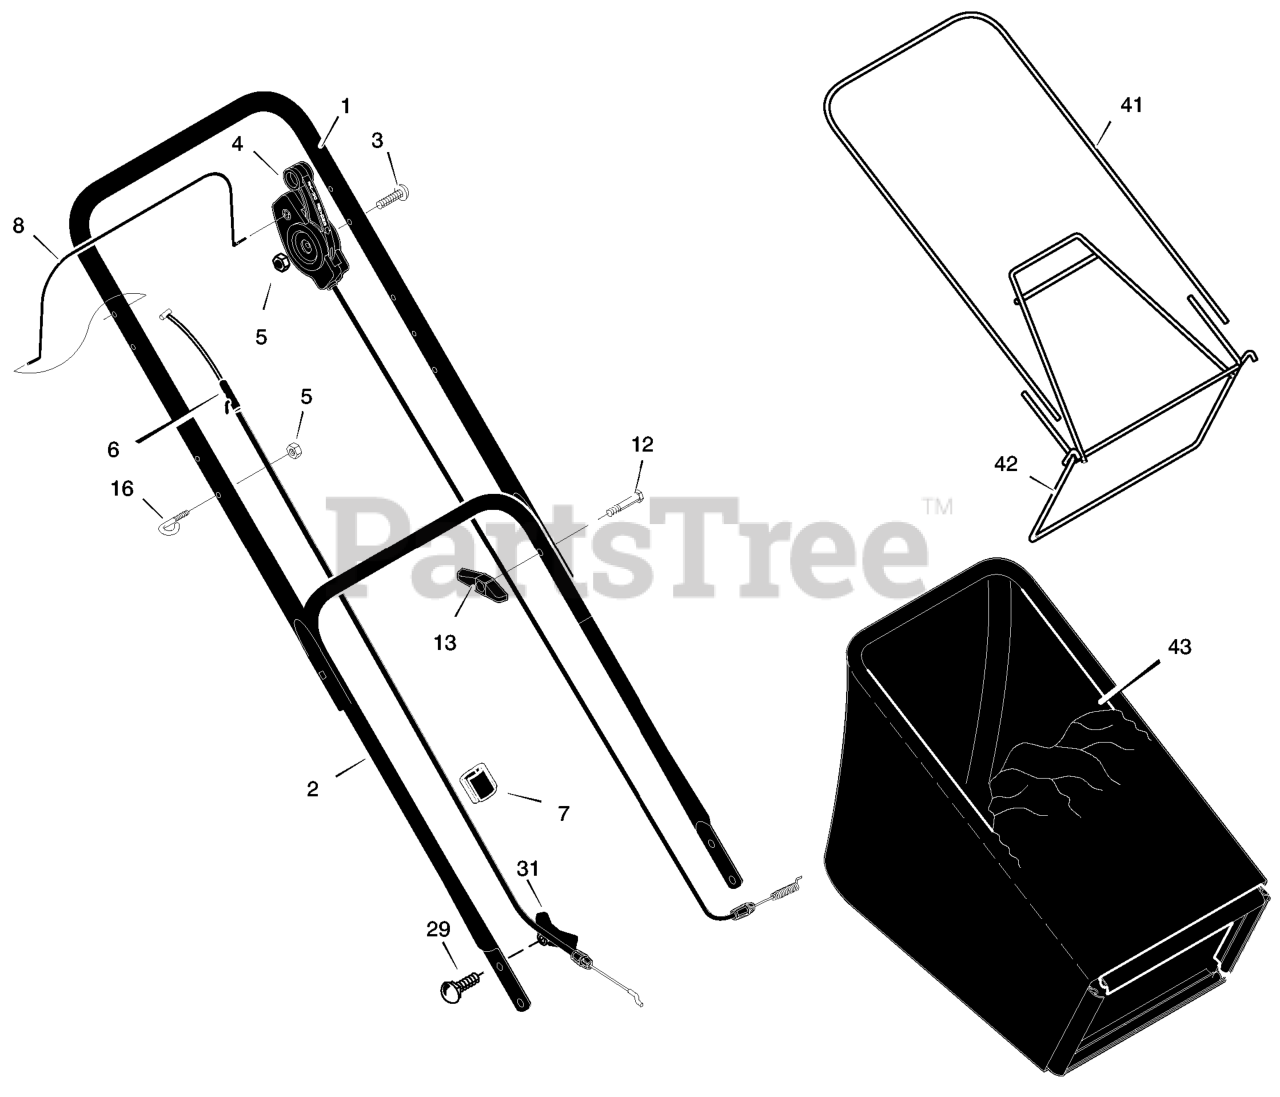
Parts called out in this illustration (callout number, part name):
1	Handle, Upper
2	Handle, Lower
4	Control, Drive
5	Locknut
6	Cable, Stop
7	Fastener, Cable
8	Lever, Stop
13	Knob
16	Guide, Rope
29	Bolt, Carriage
31	Knob, Plastic
41	Frame, Top
42	Frame Assembly
43	Bag, Cloth
